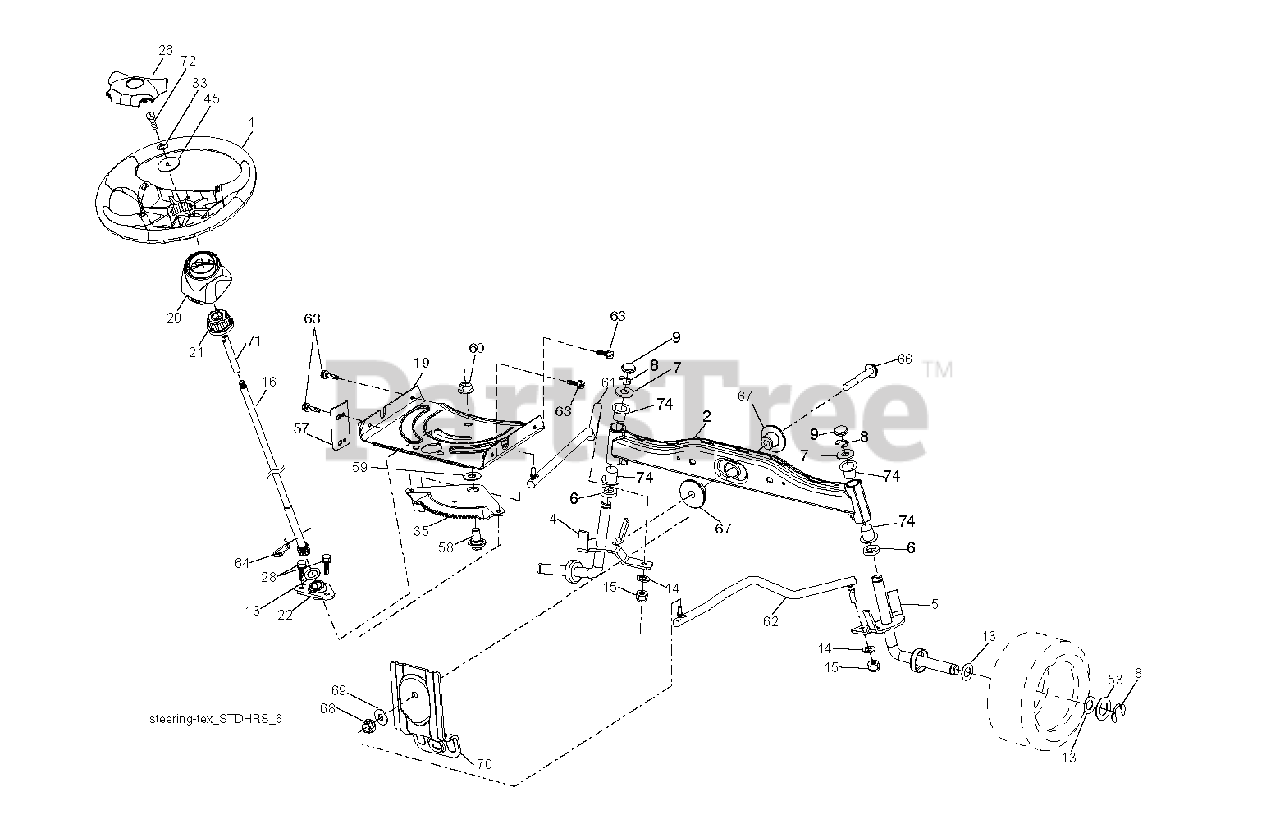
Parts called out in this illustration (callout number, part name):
1	WHEEL.STEERING.HARD.RIM.BLAC
2	AXLE HALF ASM-WELDED
4	Spindle Assembly, LH 13"
5	Spindle Assembly, RH 13"
14	WASHER, LOCK 3/8
15	NUT CROWNLOCK 3/8-24
16	SHAFT.STEER.3/4.PLATED.TEX
19	PLATE.STEER.DDL.NLT/NG
20	BOOT STEERING BLACK
21	ADAPTER, WHEEL STNG..
22	STEERING.SUPT.LOWER.
26	INSERT, WHEEL STEERING
28	SCREW, 3/8-16X3/4
35	GEAR.SECTOR.PLATE.DDL.
53	WASHER.HARDENED
57	BRACKET.UPSTOP.TEX
58	BOLT.SHOULDER.SECTOR.P
59	WASHER.THURST.SECTOR.S
60	NUT FLANGE LOCK 5/8-11
61	DRAGLINK.LH.BALLSTUD.D
62	DRAGLINK.RH.BALLSTUD.D
63	SCREW
64	RETAINER.CLIP.SPRING.S
66	BOLT HEX FGHD 7/16-14 X 3 SERR
67	BUSHING.PM.FRONT AXLE
68	NUT.LOCK.FLANGE.7/16
69	WASHER.1.5X.505X.118
70	Suspension Bracket, Front 30" Srd
71	SHAFT EXTENSION STEERING
72	BOLT 5/16-18 X 4 W/PATCH
74	BRNG T
